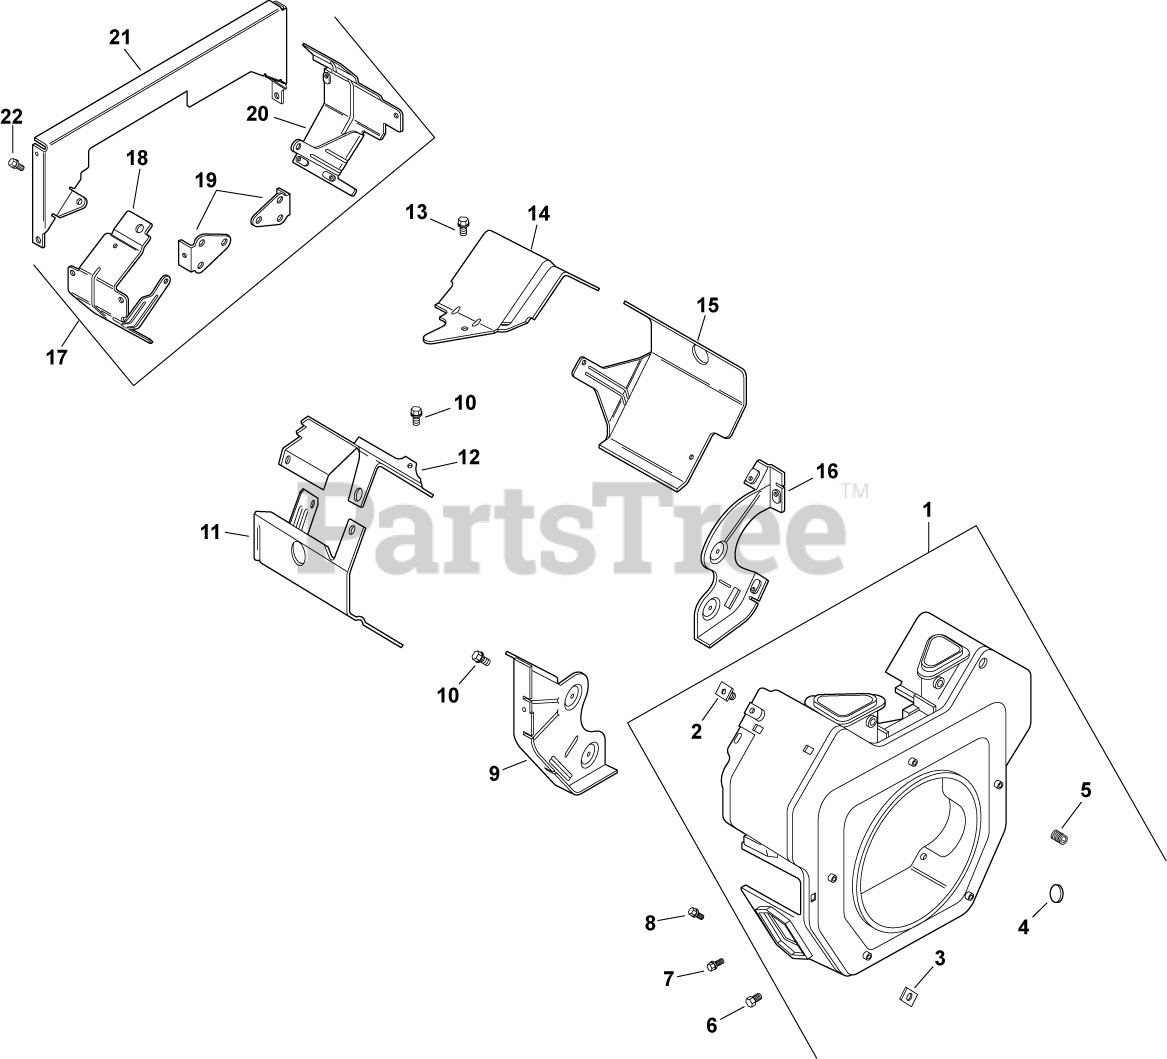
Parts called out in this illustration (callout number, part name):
1	KIT, BLOWER HOUSING ASSEMBLY USE 24 027 489-S
2	NUT, PLASTIC (KM)-USE 25 100 37-S
3	NUT, PLASTIC
4	PLUG, BUTTON 9/16
5	SCREW, SKT SET #10-24X1/4"
6	SCREW, HVY FLG M5X.8X16
7	SCREW,FLG THD FRM M5X0.8X16-(#25086398S)
8	SCREW, FLG THD FRM M5X.8X20-(#25086399S)
9	PLATE, BACKING - DISCONTINUED
10	SCREW,FLG THD FRM M6X1.0X16-(#25086397S)
12	BAFFLE, RIGHT BARREL-USE 24 063 85-S
13	SCREW, FLG THD FRM M5X.8X10
14	BAFFLE, VALLEY #2 SIDE-USE 24 063 94-S
15	BAFFLE, VALLEY (CH)-USE 24 063 93-S
16	PLATE, BACKING #2 SIDE
17	KIT, "Q"DUCT"
18	BAFFLE, DUCTED AIR-OIL FILTER
20	BAFFLE, DUCTED AIR-STARTER
21	PLATE, BACKING
22	SCREW, FLG M6X1.0X10
